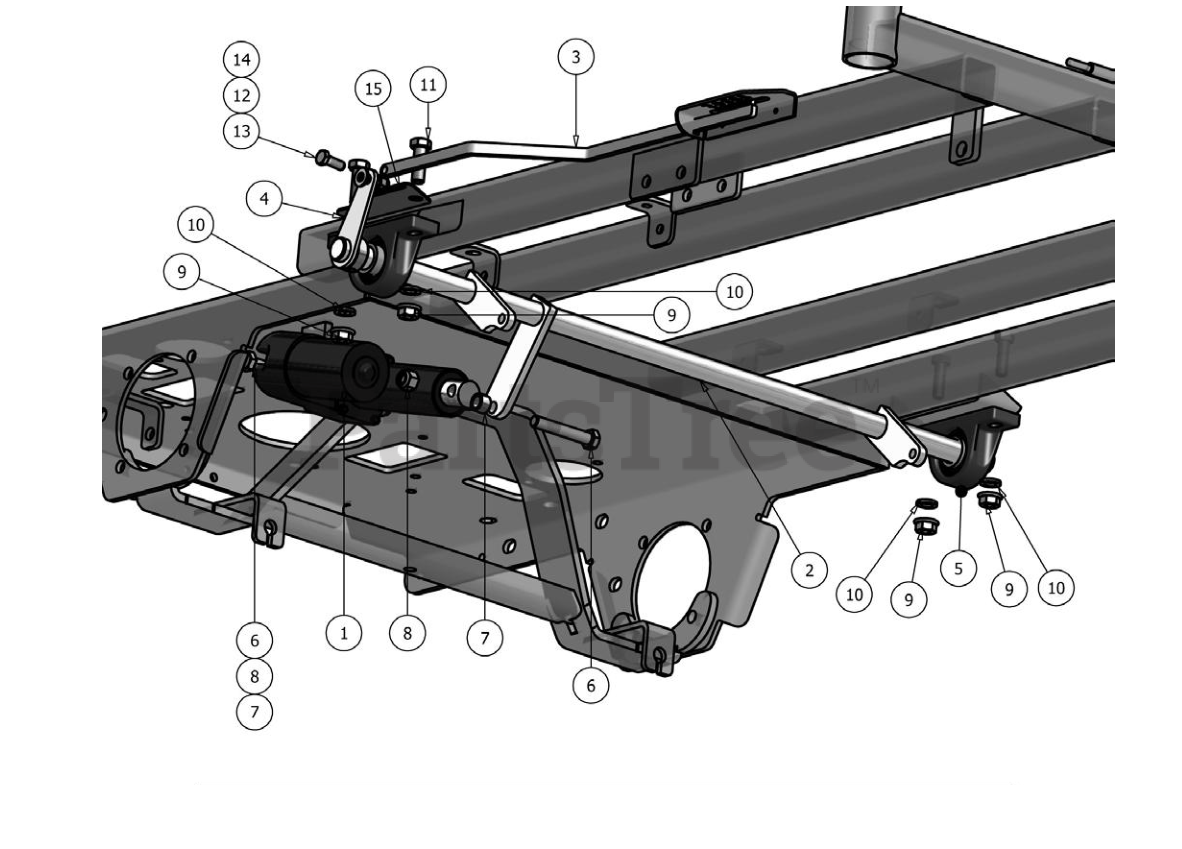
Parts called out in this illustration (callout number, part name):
2	Actuator Bar
3	Height Indicator
4	Height Indicator Tab
5	1" Pillow Block
6	1/2" x 3" Hex Bolt
7	1/2" x 1/2" Collar Spacer
8	1/2" Nylock Nut
10	1/2" Lock Washer
11	1/2" x 1 1/2" Hex Bolt
12	3/8" Plastic Washer
13	3/8" x 1" Hex Bolt
14	3/8 Nylock Nut
15	Deck Stop Bracket
